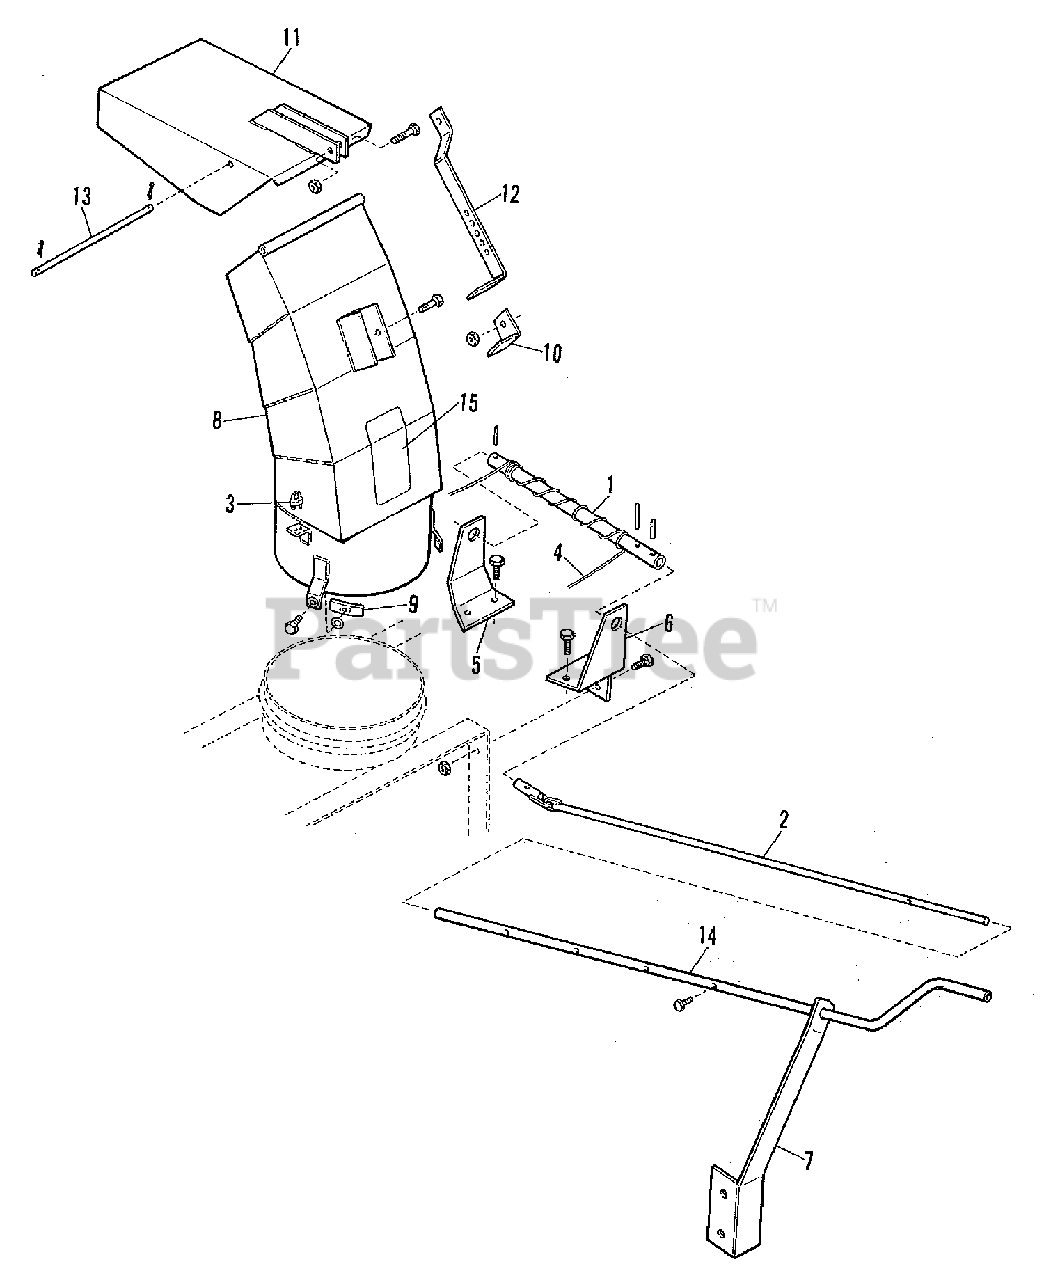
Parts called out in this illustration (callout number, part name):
1	SHAFT, Spout Rotator
1	PIN, Roll, 1/4 x 1-1/2
2	SHAFT, Adjustable
2	PIN, Roll, 1/4 x 1-1/2
3	CLAMP, Cable
4	CABLE ASSEMBLY
5	BRACKET, Front
5	CAPSCREW, 3/8NC x 1
5	WASHER, Plain, 7/16 x 1 x 14 Ga.
5	LOCKWASHER, 3/8
6	BRACKET, Rear
6	CAPSCREW, 3/8NC x 1
6	LOCKWASHER, 3/8
7	BRACKET, Handle
8	SPOUT ASSEMBLY
8	CAPSCREW, 3/8NC x 3/4
8	WASHER, Plain, 7/16 x 1 x 14 Ga.
10	LOCK, Adjuster
10	CAPSCREW, 1/2NC x 1
10	NUT, Huglock, 1/2NC
11	CAPSCREW, 1/2NC x 1-1/4
11	NUT, Huglock, 1/2NC
13	PIN, Cotter, 1/8 x 1
14	CAPSCREW, 1/4NC x 1-1/4
14	LOCKWASHER, 1/4
15	DECAL, Warning
